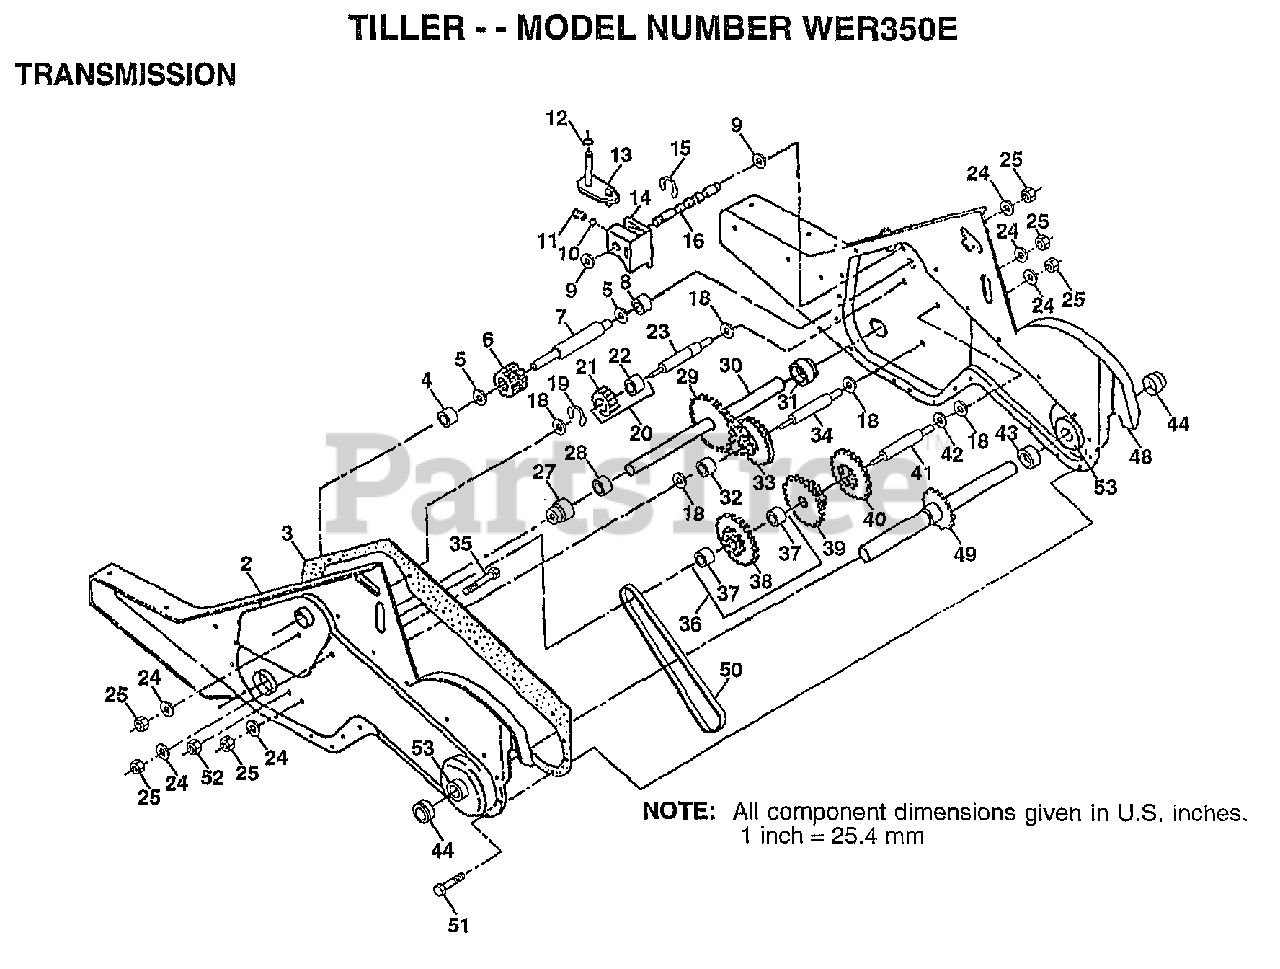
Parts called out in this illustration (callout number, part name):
2	GEARCASE LH W/BRG
3	GASKET TI
4	NEEDLE BRNG LT
5	"T, BEARING"
6	GEAR PINION INPUT
7	"SHAFT.INPUT.""D"""
8	"TI, BEARING"
9	WASHER SEAL
11	SPRING-SHIFT CRT
12	O-RING TI
13	BRACKET ASM SHIFT
14	SHIFT FORK TI
15	KLIP RING
16	SHAFT.SHIFTER
18	WASHER
19	KLIP RING
20	GEAR ASSY CRT
21	GEAR-REV IDLR CRT
22	NEEDLE BEARING TI
23	SHAFT CRT
24	LOCKWASHER
25	NUT.ASF.HEX.7/16
27	BEARING.SHAFT.LH.
28	BUSHING TI
29	CHAIN CRT
30	GROUND SHAFT ASSY
31	BEARING.SHAFT.RH.
32	SPACER TI
33	SPRCKT 8 GEAR CRT
34	SHFT 2ND RED. CRT
35	SCRW WHIZ LOK CRT
36	SPROCKET.ASM.W/BR
37	BEARING
39	GEAR TI
40	GEAR TI
41	REDUCTION SHFT TI
42	BRNG RACE
43	SPACER TI
44	SEAL ASM-OIL
48	GEARCASE RH W/BRG
49	TINE SHAFT
50	CHAIN.50 LINK TI
51	SCREW
52	NUT.HEX.5/16-18
